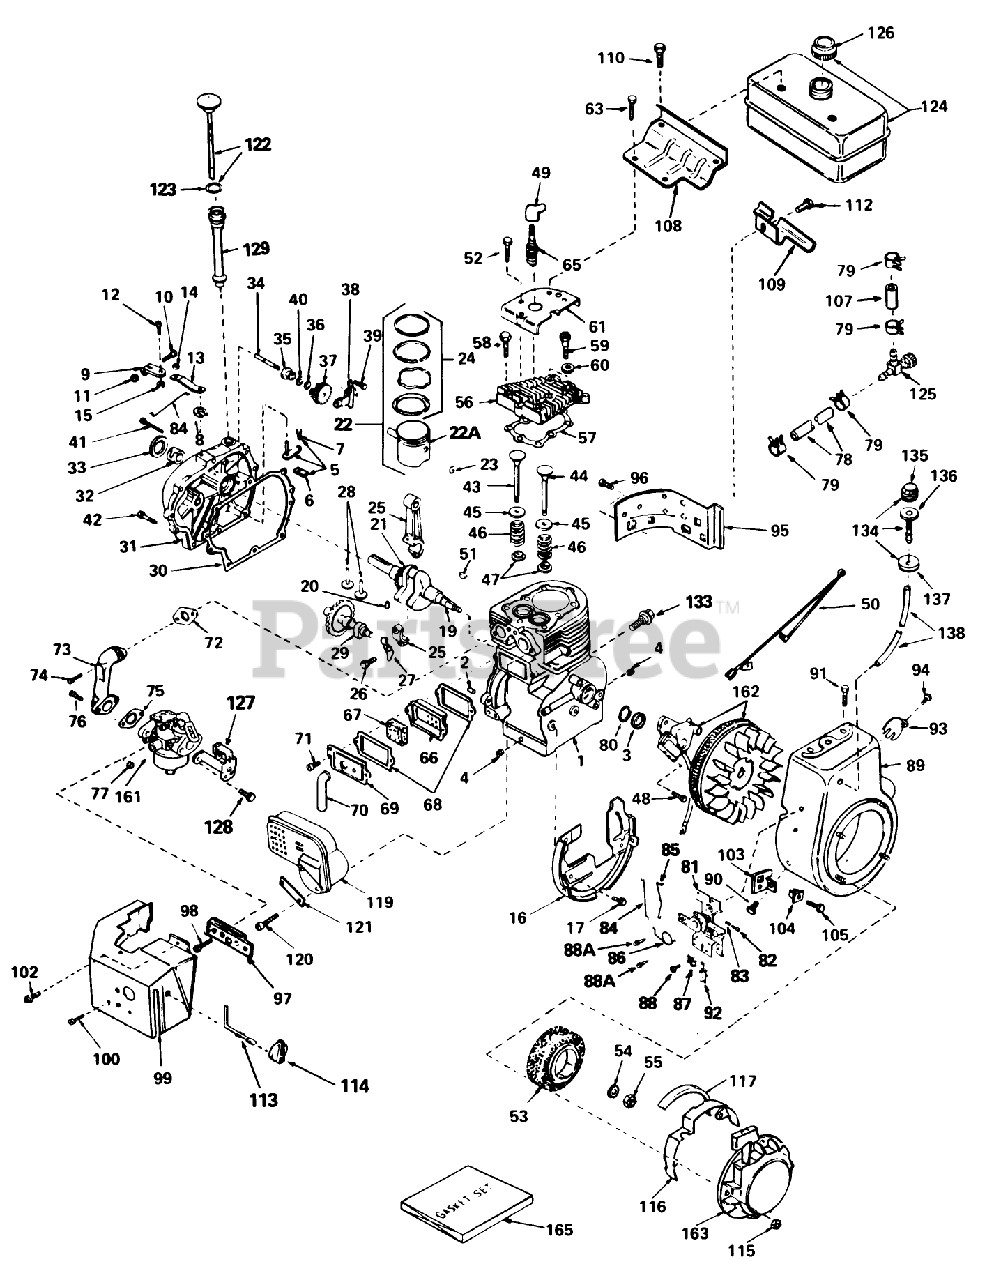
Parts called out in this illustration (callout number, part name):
1	Cylinder Assembly (Incl. Ref. #2, 3 4)
2	Pin-Dowel
3	Oil Seal
4	Plug-Drain, Oil (SQH 1/4-18)
5	Rod, Governor (Incl. Nos.62 63)
6	Yoke-Governor
7	Screw (6-40x5/16)
8	Ring-Retaining
9	Clamp-Lever, Governor
10	Screw
11	Nut-Lock
12	Screw
13	Lever-Governor
14	Washer-Lock
15	Nut-Lock
16	Baffle Blower Housing
17	Screw (1/4-20x19/32)
19	Crankshaft Assy. (Incl. Nos. 20 21)
20	Pin, Groove
21	Gear, Crankshaft
22	Piston, Pin Ring Assy.(Std.) (Incl. Ref. #24A, 25 26)
22	Piston, Pin Ring Assy. (.010 oversize) (Incl. Ref. #24A, 25 26)
22	Piston, Pin Ring Assy. (.020 oversize) (Incl. Ref. #24A, 25 26)
22A	Piston Pin Assy. (Std.) (Incl. Ref. #26)
22A	Piston Pin Assy. (.010 oversize) (Incl. Ref. #26)
22A	Piston Pin Assy. (.020 oversize) (Incl. Ref. #26)
24	Ring Set (Std.)
24	Ring Set (.010" OS)
24	Ring Set (.020" OS)
25	Rod Assy., Connecting (Incl. Nos. 10 18)
26	Bolt, Connecting Rod
27	Dipper-Oil
28	Lifter-Valve
29	Camshaft (Mech. Comp. Release)
30	Gasket, Cylinder Cover
31	Cover, Cylinder (Incl. Ref. #32, 33 34)
32	Bushing, Crankshaft
33	Seal, Oil
34	Shaft-Governor
35	Spool-Governor
36	Ring-Retaining
37	Governor Gear ASM
38	Bracket-Gear, Governor
39	Screw (10-32 x 35/64)
40	Washer-Flat
41	Screw (1/4-20 x 1-1/4)
42	Screw
43	Valve, Intake (Std.) (Incl. Ref. #58)
43	Valve, Intake (1/32" oversize) (Incl. Ref. #58)
44	Valve, Exhaust (Standard)(Incl. No. 9)
44	Valve, Exhaust (1/32" oversize)(Incl. No. 9)
45	Cap-Spring, Valve
46	Spring-Valve
47	Keeper-Spring, Valve
48	Screw
49	Cover-Spark Plug
50	Wire, Ground
51	Key-Flywheel
52	Screw (1/4-20 x 1/2)
53	Hub Screen Assy., Starter
54	Washer
56	Head Cylinder
57	Gasket-Cylinder Head
58	Screw (5/16-18x1-1/2)
59	Screw (5/16-18x1-25/32)
60	Washer-Flat
61	Cover, Cylinder Head
63	Screw
65	Plug, Spark (J17LM or equiv.)
65	Plug, Spark (Champion RCJ-8)
66	Body-Breather
67	Element-Breather
68	Gasket-Breather
69	Cover-Valve
70	Tube-Breather
71	Screw
72	Gasket-Intake
73	Pipe-Intake
74	Screw (T-30, 5/16-18x1-3/32)
75	Gasket, Carburetor
76	Screw (1/4-28x1)
77	Nut and Lock Washer (1/4-28)
78	Line-Fuel
79	Clamp-Line, Fuel
80	Gasket Stator
81	Control Assy., Remote Speed (Incl. Ref. #90 thru 93)
82	Screw
83	Spring-Compression
84	Link-Governor
85	Link-Throttle
86	Spring-Throttle
87	Conduit
88	Screw (10-32 x 3/8)
88A	Screw (10-32 x 1/2)
89	Housing, Blower
90	Screw, Hex Hd.
91	Screw (5/16-18x3/4)
92	Terminal
93	Screw
94	Screw (8-32 x 3/8)
95	Extension, Blower Housing
96	Screw
97	Bracket-Carburetor
98	Screw (8-32x27/64)
99	Cover, Carburetor
100	Screw (10-32 x 3/8)
102	Screw (10-32x1/2)
103	Bracket
104	Grommet
105	Screw
107	Line-Fuel (8.62)
108	Bracket-Tank, Fuel (Black)
109	Bracket-Tank, Fuel
110	Screw (1/4-15x7/8)
112	Screw (1/4-20x19/32)
113	Rod-Choke
114	Knob-Control
115	Nut and Lock Washer (1/4-28)
116	Guard, Starter
117	Seal, Snowguard
119	Muffler
120	Screw, Hex Hd.
121	62513 SNWTHWR W/284
122	Dipstick, Oil (Incl. Ref. #88)
123	O-Ring
124	Tank Assy., Fuel (Incl. No. 115)
125	Valve-Shut Off
126	Cap, Fuel
127	Bracket-Choke
128	Screw (10-32 x 1/2)
129	Tube Fill
133	Screw (1/4-20x1/2)
134	Primer Assy. (Incl. Nos. 89, 90 91)
135	Bulb, Primer
136	Body, Primer
137	Retainer, Primer Bulb
138	Line, Primer
161	Carburetor (Incl. Ref. #75)
162	Magneto (The complete magneto is not available as an assembly. The magneto number is shown for reference purposes only. Order component parts individually, as shown in parts list.)
163	Starter, Rewind
165	Gasket Set
